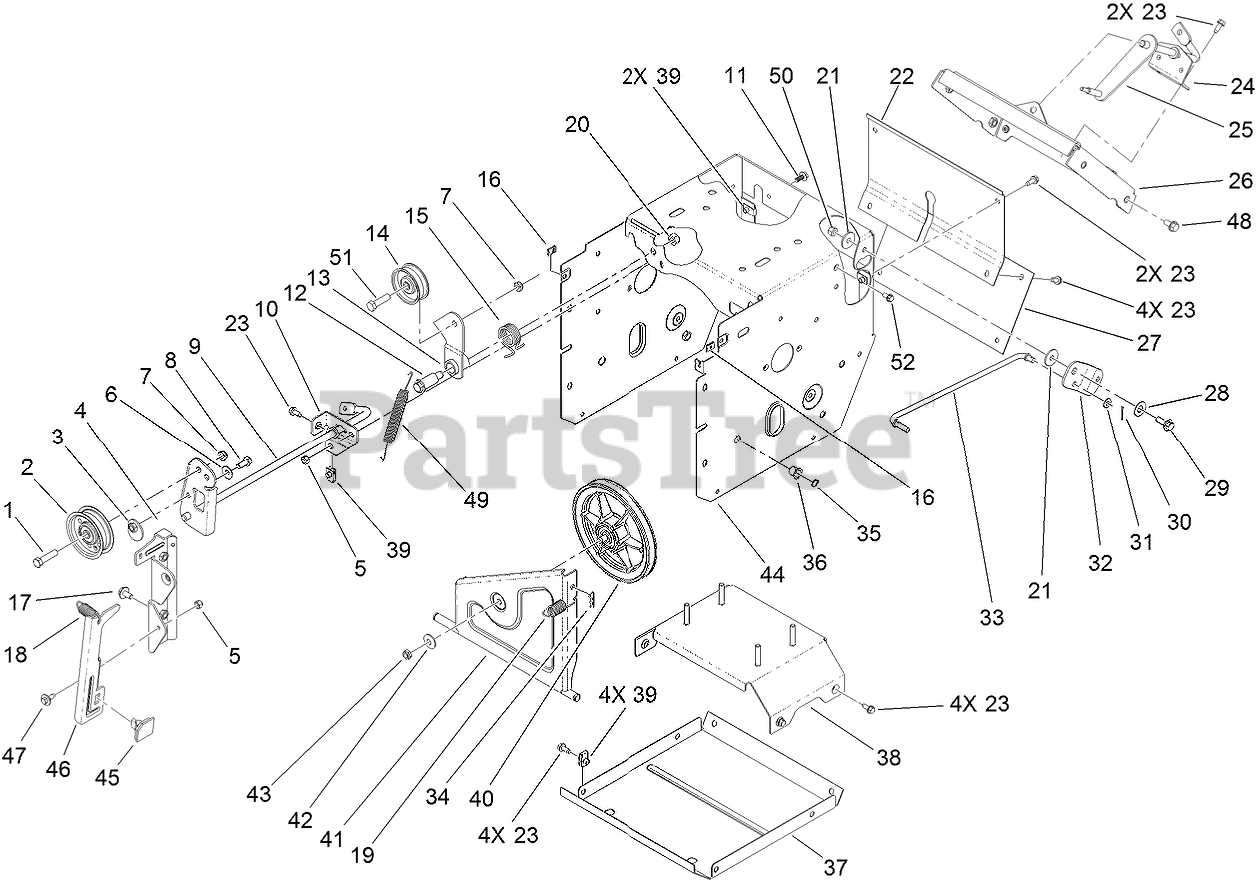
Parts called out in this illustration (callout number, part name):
1	SCREW-HH
2	PULLEY-IDLER
4	BRACKET-IDLER, IMPELLER
5	NUT-LOCK, NI
6	WASHER-BELLEVILLE
7	NUT-LOCK, NI
8	SCREW-HH
9	IMPELLER CLUTCH ASM
10	BRACKET-CLUTCH, IMPELLER
11	SCREW-HHF
12	BOLT-SHOULDER
13	ARM-IDLER, TRACTION
14	PULLEY-IDLER
15	SPRING-TORSION
16	NUT-SPEED, U-TYPE
17	SCREW-HHF
18	SPRING-EXTENSION
19	SPRING-EXTENSION
20	NUT-LOCK, NI
21	WASHER-PIVOT
22	COVER-UPPER
23	SCREW-HWH
24	BRACKET-ROD, SHIFT
25	LEVER-CONTROL, TRACTION
26	SHIFT PLATE ASM
27	COVER-LOWER
28	WASHER
29	SCREW-SHOULDER
30	PIN-COTTER
31	WASHER-PLAIN
32	BELLCRANK-DRIVE
33	LINK-CONTROL, SPEED
34	PIN-COTTER
35	RING-RETAINING
36	BUSHING-NYLINER
37	PAN-BOTTOM
38	FRAME BRACE ASM
40	PULLEY-TRACTION
41	BRACKET-WHEEL, FRICTION
42	WASHER-BELLEVILLE
43	NUT-HEX
44	FRAME-TRACTION
45	PAD-BRAKE
46	ARM-BRAKE
47	SCREW-SHOULDER
48	SCREW-HWHTF
49	SPRING-EXTENSION
50	NUT-LOCK, NI
51	SCREW-HH
52	SCREW-HWH
